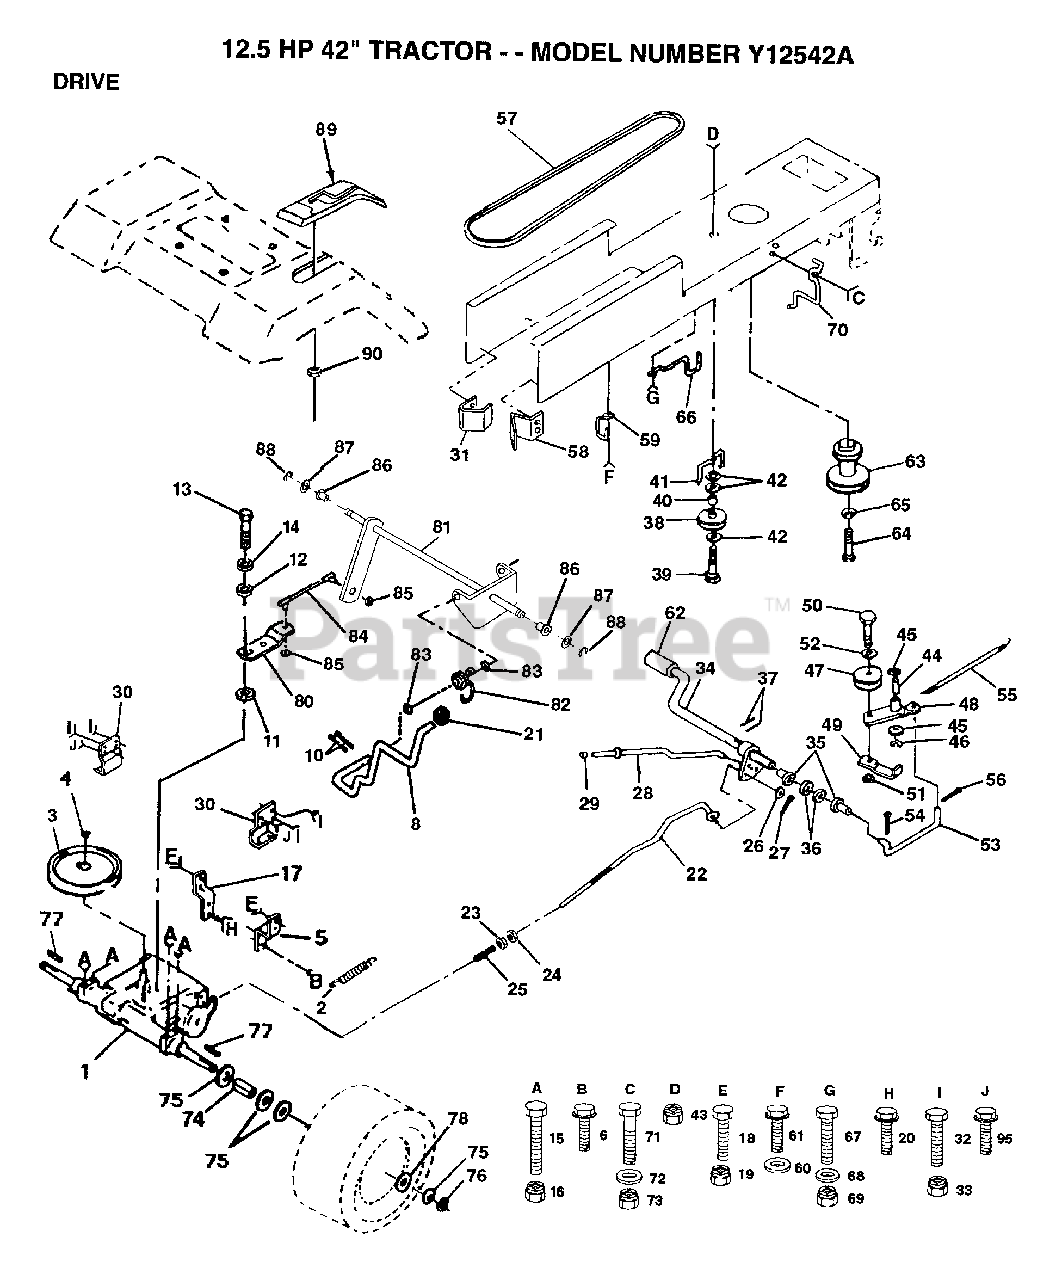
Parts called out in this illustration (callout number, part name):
3	PULLEY TRANS
5	STRAP TORQUE
6	SCREW
10	PIN COTTER 1/8
11	WASH-SHFT PLT LT
12	WASHER
14	LOCKWASHER
15	BOLT
17	STRAP TORQUE
20	SCREW
21	KNOB T (1/2-HOLE)
22	BRAKE ROD
23	NUT
24	NUT
25	SPRING ROD LT
26	WASHER
27	COTTER PIN
28	PARKING BRAKE ROD
29	PLUNGER CAP T
30	TRANSAXLE MTG BKT
31	"KEEPER,BELT LH T"
32	BOLT
35	NYLON BEARING
36	WASHER LT
38	PULLEY.IDLER.FLAT
39	BOLT
40	SPACER T
41	BELT KEEPER LT
42	WASHER
44	"LY, BEARING"
45	WASHER LT
46	KLIP RING
48	ARM IDLER
49	RETAIN BELT
52	WASHER
53	"LINK, CLUTCH T"
54	COTTER PIN
55	"SPRING, RETURN LT"
56	COTTER PIN
57	BELT.V.GDRIVE.95
58	"KEEPER,BELT RH T"
60	WASHER
61	SCREW
62	PEDAL COVER T
64	BOLT
65	LOCKWASHER
66	KEEPER.BELT.ENG.L
67	BOLT
68	WASHER
70	KEEPER BELT ENG
71	BOLT
72	WASHER
74	SPACER LT
75	WASHER
76	E-RING LT
77	SQUARE KEY
78	WASHER
80	SHIFT LEVER
81	SHAFT ASM SHIFT
82	"SPRING,TORSION"
83	WASHER
84	TIE ROD
85	NUT 1/4-28
86	BUSHING
87	WASHER D
88	KLIP RING
90	NUT
95	SCREW
